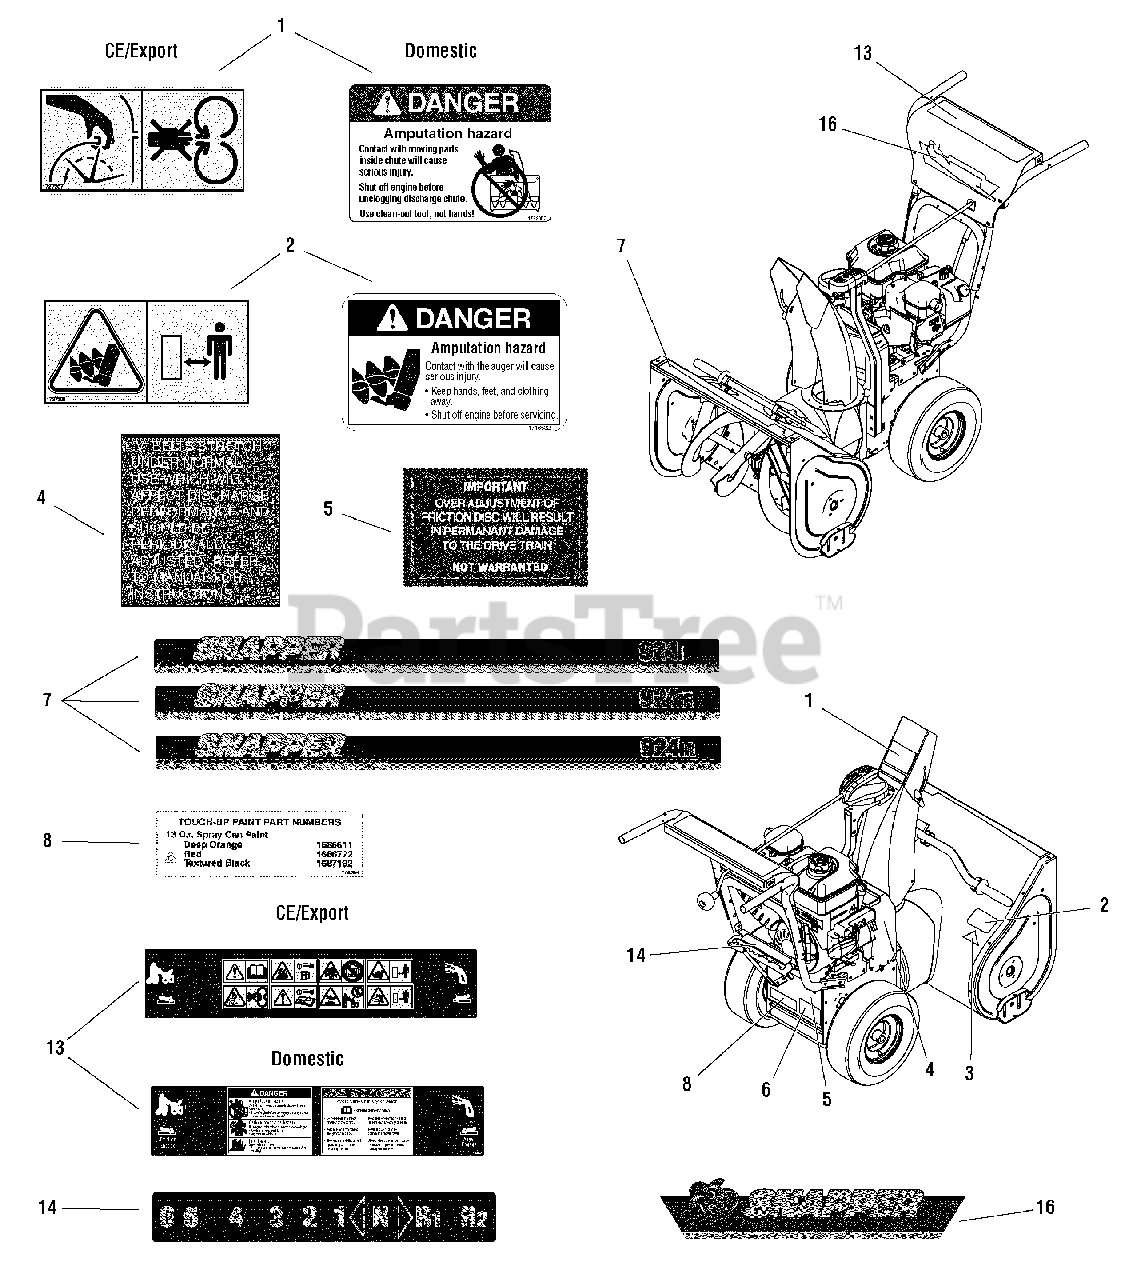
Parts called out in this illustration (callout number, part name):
1	DECAL, Chute Warning
1	DECAL, Danger Amputation Hazard
2	DECAL, Impeller Warning
2	DECAL, Danger Avoid Injury, Auger
3	*DECAL, OPEI
4	DECAL, Belt Stretch and Adjustment
5	DECAL, Over Adjust of Friction Disc
6	*STICKER, Serial w/Bar Code
7	DECAL, Snapper 924IE
7	DECAL, Snapper 924IR
7	DECAL, Snapper 924I
8	DECAL, Touch Up Paint
13	DECAL, Dash
14	DECAL, Speed Control
16	DECAL, Snapper w/Icon
